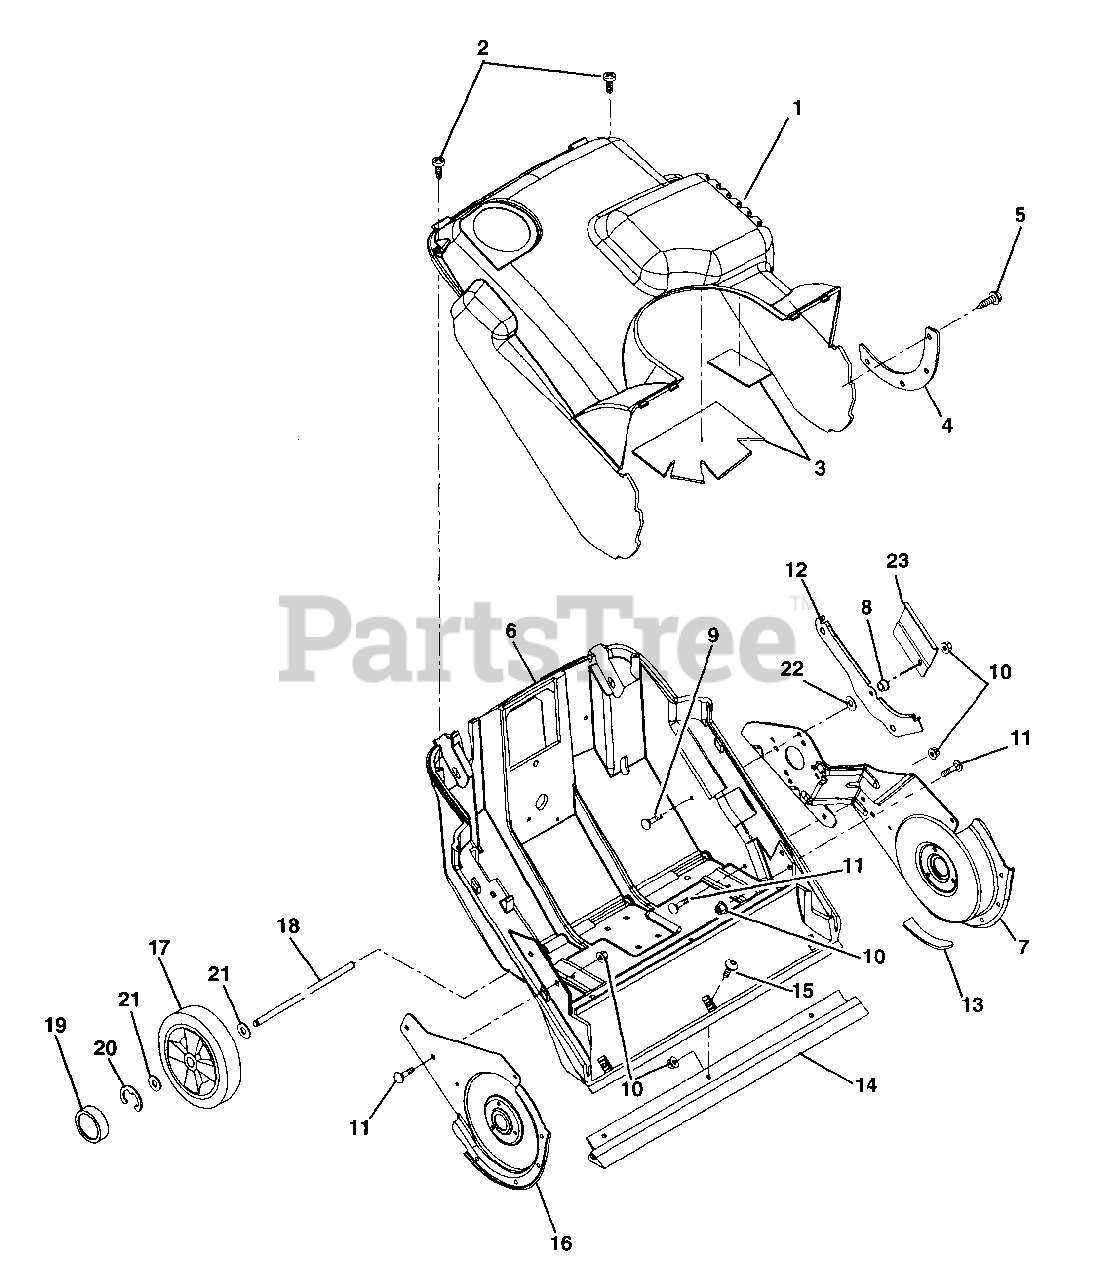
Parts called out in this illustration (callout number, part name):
1	COWL ASSY-REPLACEMENT
2	SCR-SPEC-TAP #10X1.0
3	SHEET-HEAT REFLECTIVE
4	PLATE-COWL RETAINER
5	SCR-TAP 12-24X.50 HWH TR BLACK
6	CHASSIS
7	SUPPORT-BRG,LH
8	BSHG-FLG .265X.437X.250X.750
9	@BLT-RDHDSQNK .25-20X1.25 G5YZ
10	NUT-LK-FLG .250-20 PL BLK
11	@BLT-RDHDSQNK .25-20X.75 G5YZ
12	GUIDE-CABLE
13	TAPE, ADH. BACKED FOAM - 1.75
14	BLADE-SCRAPER
15	SCR-MCH .25-20X.75 TXTR YWZC
16	SUPPORT-BRG,RH
17	T/WHL ASSY 7.0X1.5
19	CAP-HUB
20	RG-RTNG-EXT .375X.035 TYP E
21	@WSHR-FL-STL.406X.812X.065 YWZ
22	@WSHR-FL-STL.312X.734X.065 YWZ
23	DEFLECTOR, EXHAUST
